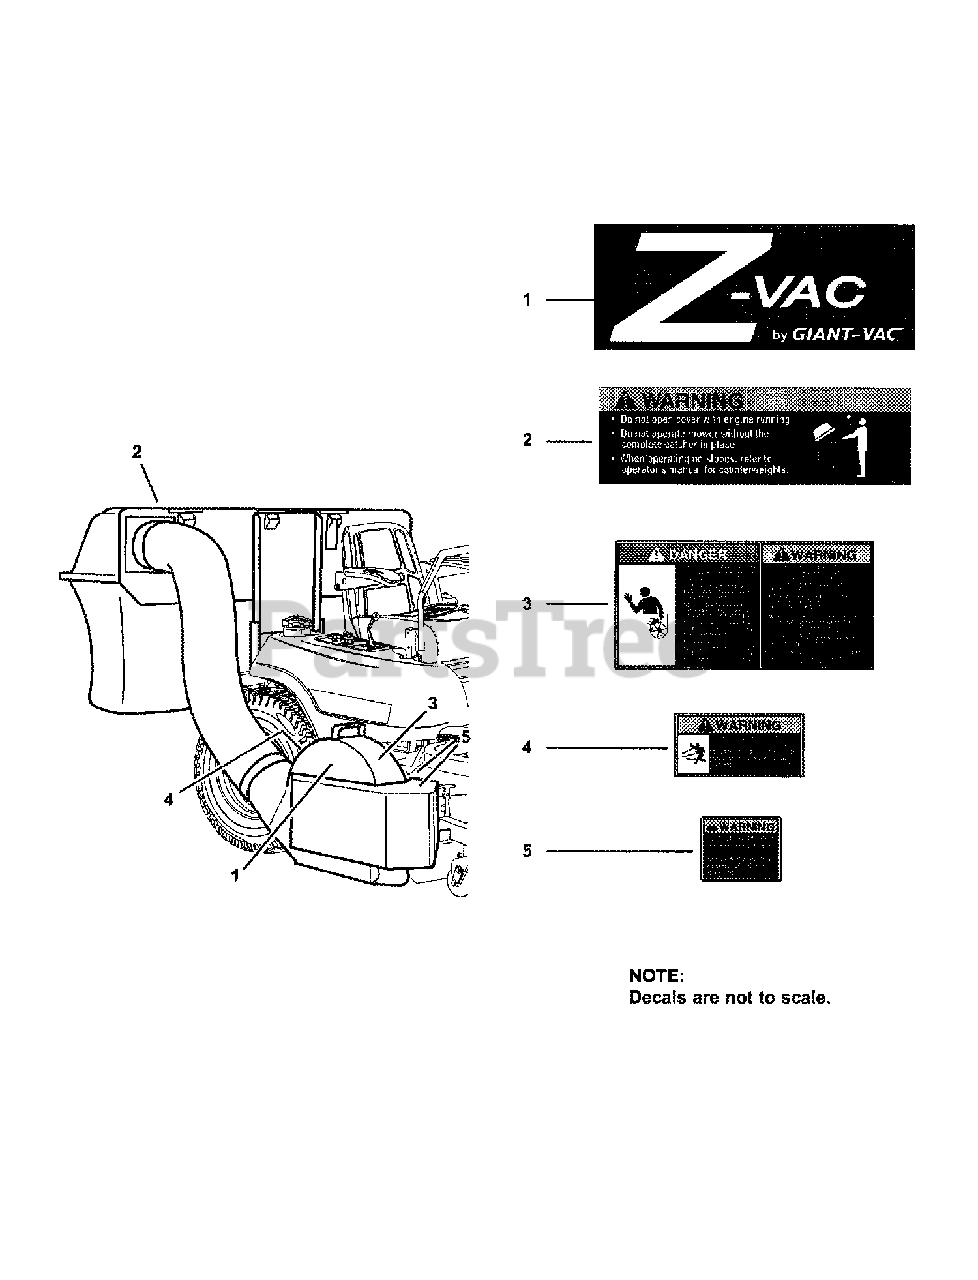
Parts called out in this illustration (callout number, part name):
1	DECAL, Fast-Vac
2	DECAL, Safety, Grass Bag
3	DECAL, Danger, Fast-Vac
4	DECAL, Warning, Fast-Vac
5	DECAL, Warning, Fast-Vac
